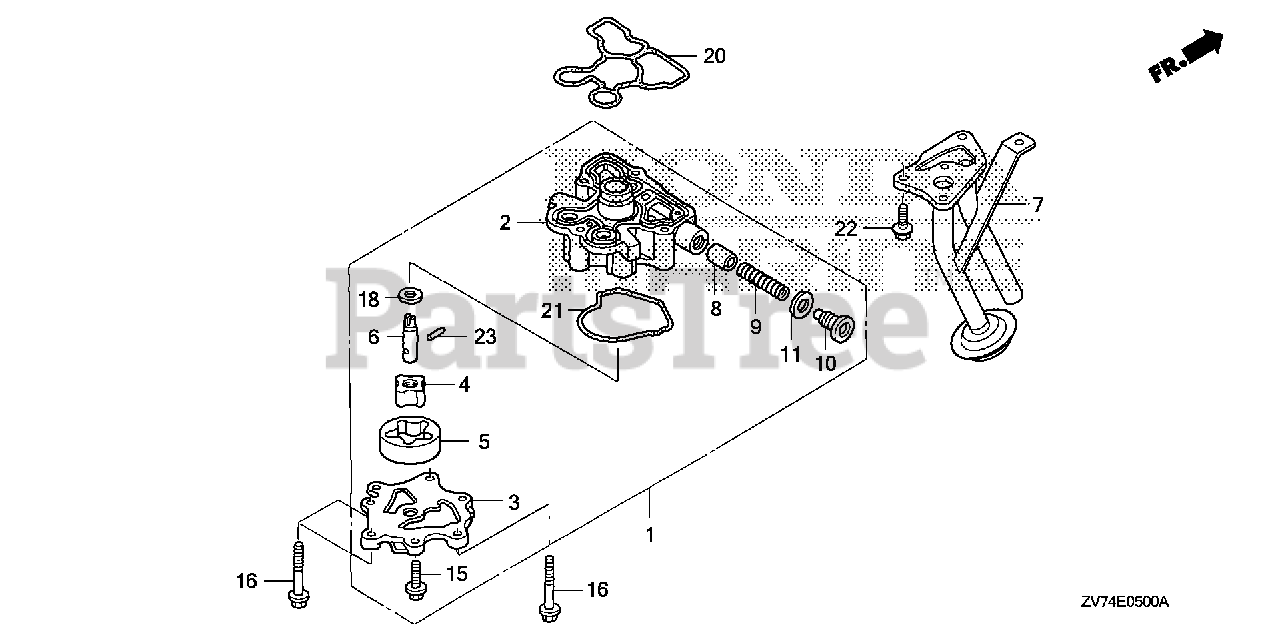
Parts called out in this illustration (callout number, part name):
1	PUMP ASSY., OIL
2	BODY, OIL PUMP
3	COVER, OIL PUMP
4	ROTOR, OIL PUMP (INNER)
5	ROTOR, OIL PUMP (OUTER)
6	SHAFT, OIL PUMP
7	STRAINER, OIL
8	VALVE, RELIEF
9	SPRING, RELIEF VALVE
10	BOLT, SEALING (14MM)
11	WASHER, SEALING (14MM)
13	GASKET, EX. PIPE
14	GROMMET, WATER TUBE
15	BOLT, FLANGE (6X18) (CT200)
16	BOLT, FLANGE (6X45)
17	BOLT, HEX. (8X25)
18	WASHER, THRUST (11MM)
19	WASHER, PLAIN (8MM)
20	O-RING, PUMP COVER
21	O-RING, PUMP COVER
22	BOLT, FLANGE (6X16)
23	ROLLER (4X15.8)
